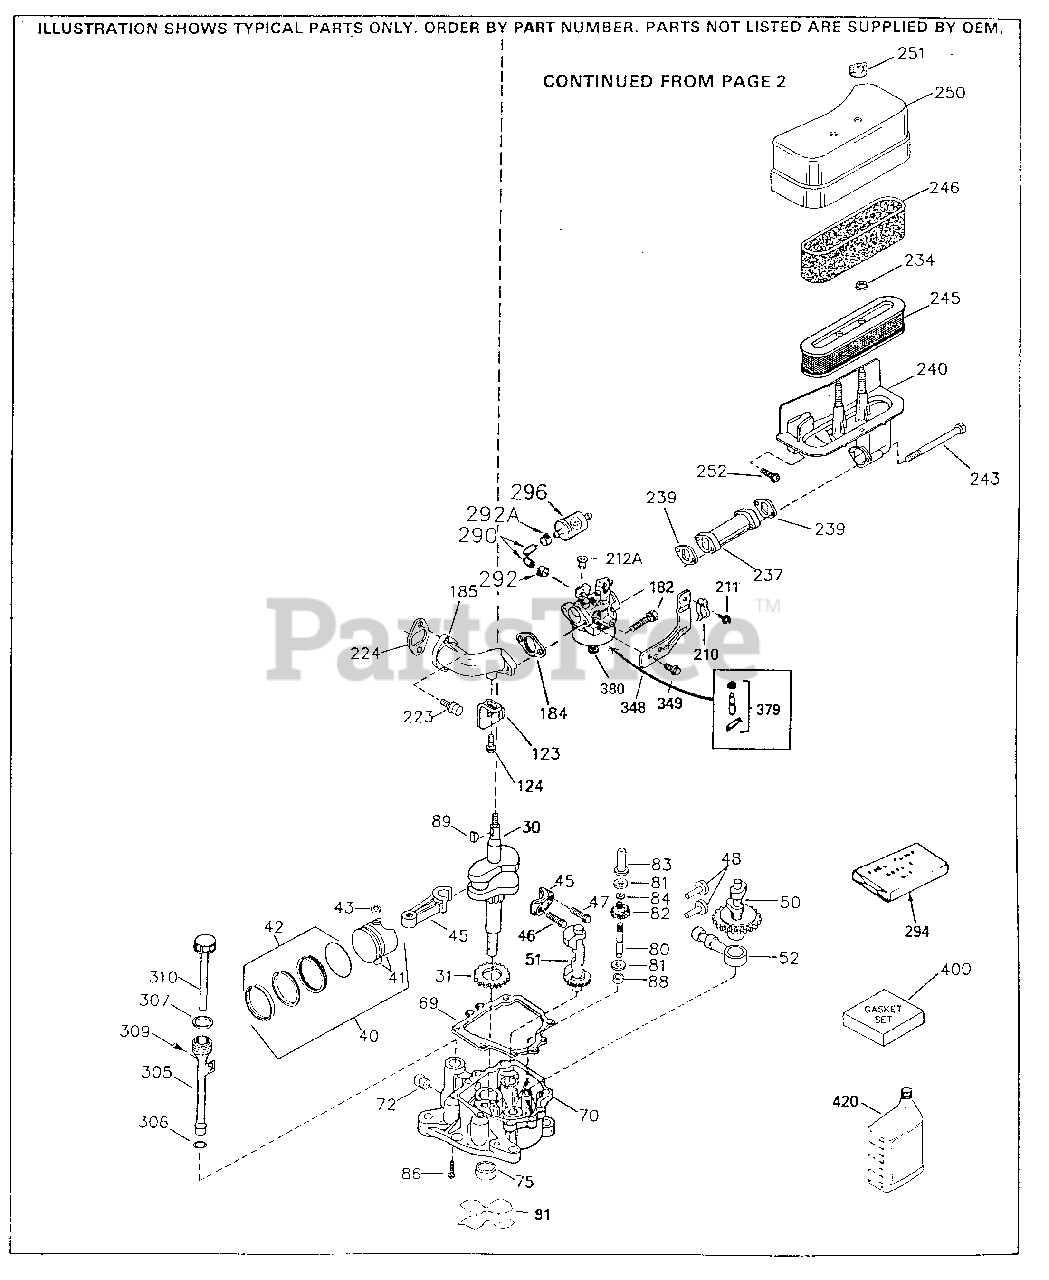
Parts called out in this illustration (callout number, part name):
30	Crankshaft
31	Counterbalance Gear
39	Lock Nut, 8-32
40	Piston, Pin & Ring Set (Std.)Nos. 41, 42 & 43)
40	Piston, Pin & Ring Set (.010" OS)Nos. 41, 42 & 43)
40	Piston, Pin & Ring Set (.020" OS)Nos. 41, 42 & 43)
41	Piston & Pin Ass'y. (Std.) (Incl. 43) No. 43)
41	Piston & Pin Ass'y. (.010" OS) (Incl. (Incl. No. 43)
41	Piston & Pin Ass'y. (.020" OS) (Incl. (Incl. No. 43)
42	Ring Set (Std.) (3-5/16")
42	Ring Set (.010" OS)
42	Ring Set (.020" OS)
45	Connecting Rod Ass'y. (Incl. 46 & 47) 46 & 47)
46	Bolt, Connecting Rod
47	Bolt, Connecting Rod
48	Valve Lifter
50	Camshaft
51	Counterbalance Weight
52	Oil Pump (Mach)
69	Engine Mounting Flange Gasket
70	Engine Mounting Flange Incl. Nos.72, 75 & 80
72	Oil Drain Plug
75	Oil Seal
80	Governor Shaft
81	WASHER
82	Governor Gear Assembly
83	Governor Spool
84	Retaining Ring
86	Screw, Hex Washer Hd. Powerlok, 1/4-2 0 x 1-3/16
88	Governor Gear Spacer
89	Flywheel Key
123	Intake Pipe Brace
124	Screw, Hex Washer Spinlock Hd., Threa d Forming, 1/4-20 x 5/8
182	Screw, Hex Sems, 1/4-20 x 27/32
184	Carburetor to Intake Pipe Gasket
185	Intake Pipe (Mach)
210	Conduit Clip
211	Screw, 10-32 x 3/8" 3/8
223	Screw, Hex Hd. Sems, 5/16-18 x 7/8
224	Intake Port Gasket
225	Air Filter Adapter
234	Air Cleaner Nut
239	Air Cleaner Elbow Gasket
240	Air Cleaner Body Assy. Inc. No.239
243	Screw, Fil. hd. Sems, 10-32 x 5-1/4
245	Air Filter (Incl. 234) also available in Packaged Part #740015B
246	Pre-Cleaner Air Filter also available in Packaged Part #740015B
250	Air Cleaner Cover
251	Wing Nut
252	Screw, Hex Washer Hd. Self-Drill, Sel f-Tap, 1/4-20 x 1
261	Screw, T-30, 1/4-20 x 1/2" Sems, 1/4- 20 x 1/2
290	Fuel Line (11.00")
292	Fuel Line Clamp
292A	Fuel Filter Clamp
296	Fuel Filter (Incl. 292) also availabl e as Packaged Part #740003B
305	Oil Fill Tube
306	Fill Tube Gasket
307	"O" Ring
309	Shoulder Screw, Hex washer hd. should er, 5/16-24 x 25/32
310	Oil Gage & Cap Assy.
316	Alternater Coil (3 Amp D.C. System)(I ncl. Nos. 321, 322B & 323A)
380	Carburetor (Incl. No. 184)
